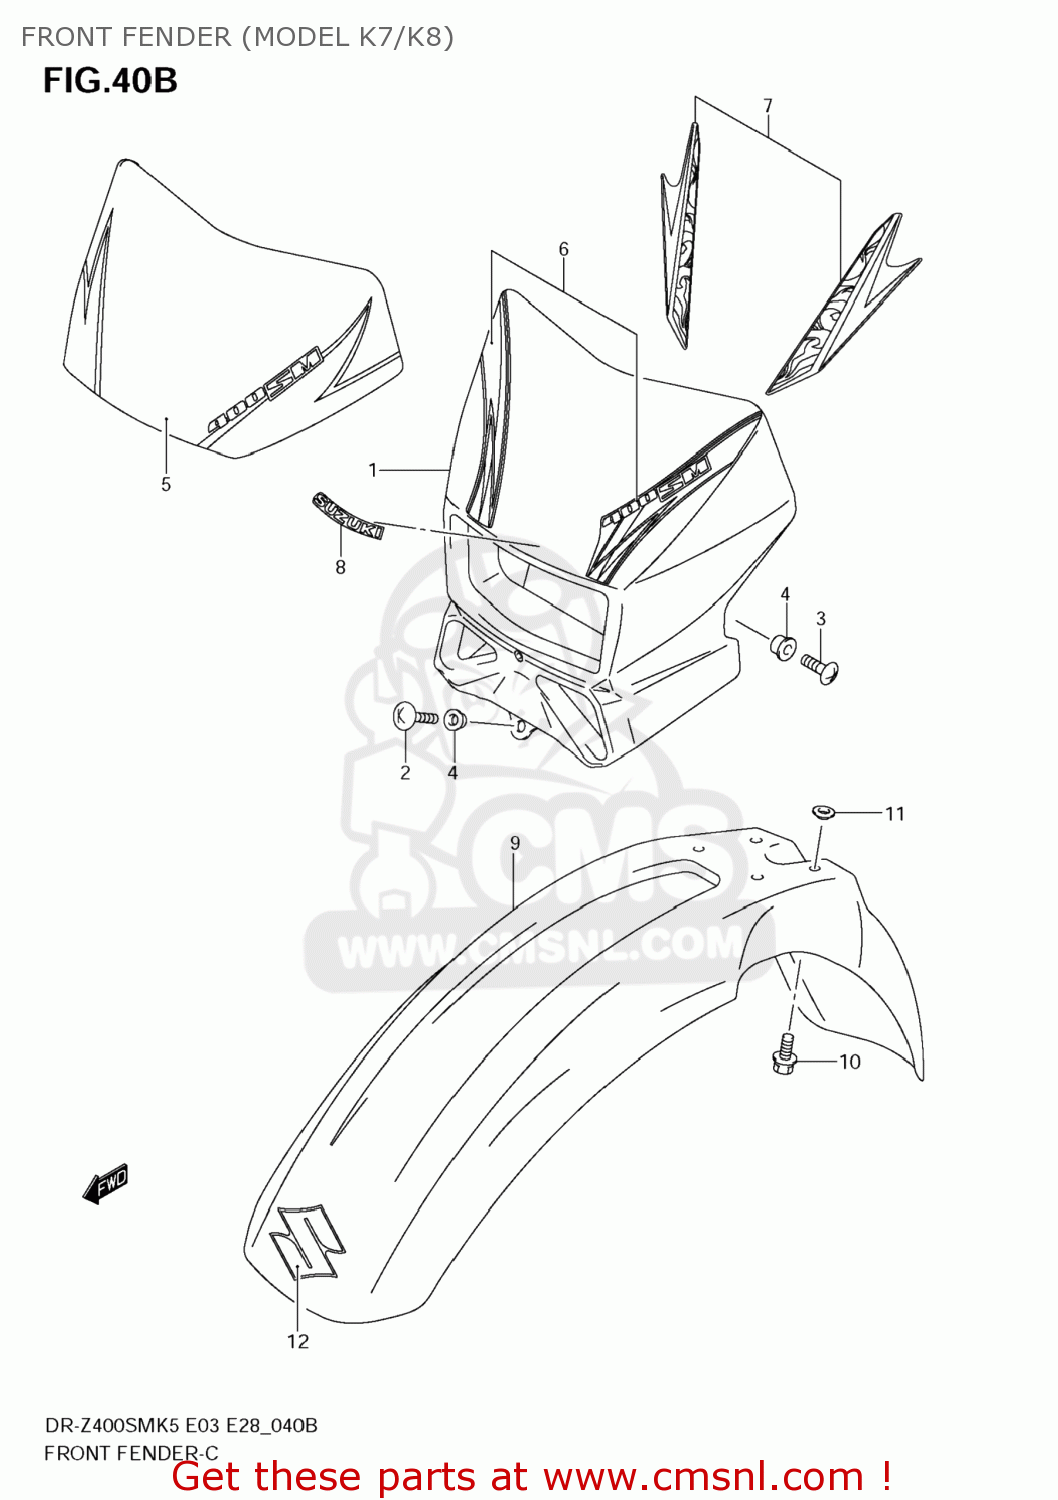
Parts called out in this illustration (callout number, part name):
1	COVER,HEADLAMP
2	SCREW
3	SCREW
4	WASHER
5	TAPE,HEADLAMP HOUSING
6	TAPE SET,HEADLAMP HOUSING
7	TAPE SET,HEADLAMP HOUSING
8	EMBLEM,SUZUKI
9	FENDER,FR
10	BOLT(6X16)
11	WASHER
12	EMBLEM,S
